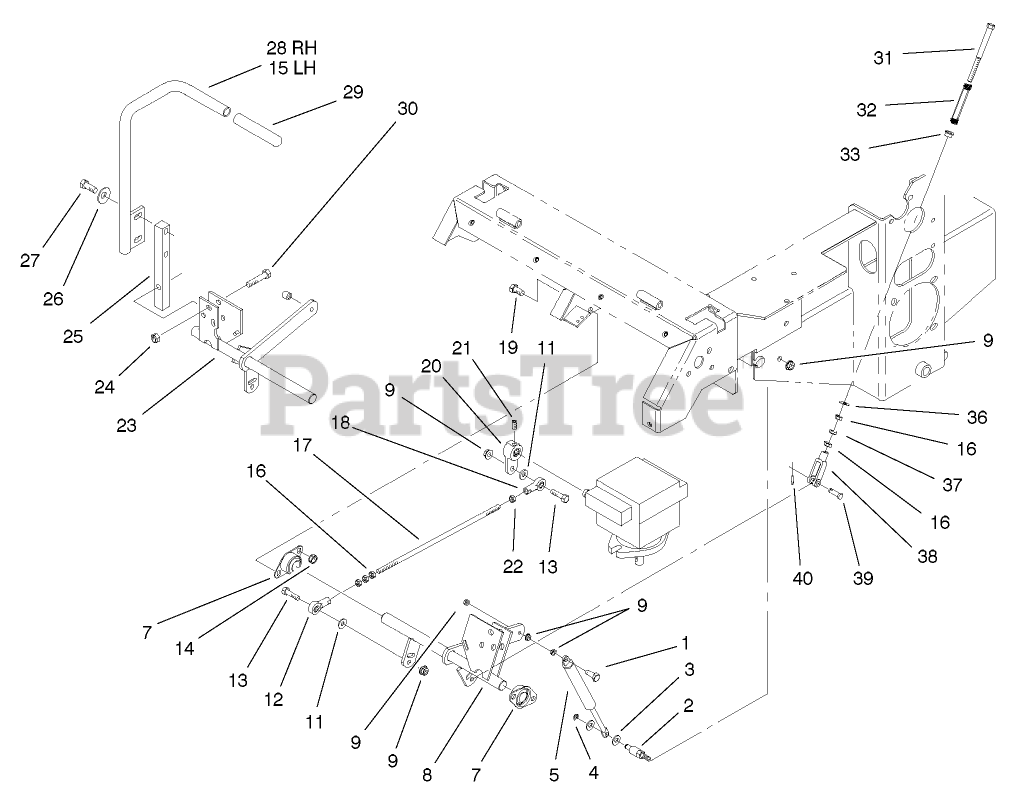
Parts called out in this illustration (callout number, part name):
1	SCREW-HH
2	PIN-DAMPER
3	WASHER-PLAIN
4	RING-RETAINING, EXT
5	DAMPER-CONTROL
7	BEARING-FLANGE, SIDE
8	CONTROL-MOTION, LH
9	NUT-HF
11	WASHER-FLAT
12	BALLJOINT-RH
13	SCREW-HH
14	NUT-HHF, WHIZ
15	LEVER-CONTROL, LH
16	NUT-HEX
17	LINKAGE-PUMP/LEVER
18	BALLJOINT-LH
19	SCREW-HH
20	ARM-CONTROL, PUMP
21	SCREW-SET
23	CONTROL-MOTION, RH
24	NUT-LOCK, NI
25	ARM-CONTROL, SHAFT
26	WASHER-BELLEVILLE
27	SCREW-HH
28	LEVER-CONTROL, RH
29	GRIP-CONTROL, MOTION
30	SCREW-HH
31	BOLT-RETURN, NEUTRAL
32	SPRING-RETURN, NEUTRAL
33	BUSHING-FLANGED
36	WASHER-FLAT
37	NUT-JAM
38	YOKE-ADJUSTABLE
39	PIN-CLEVIS
40	PIN-COTTER
